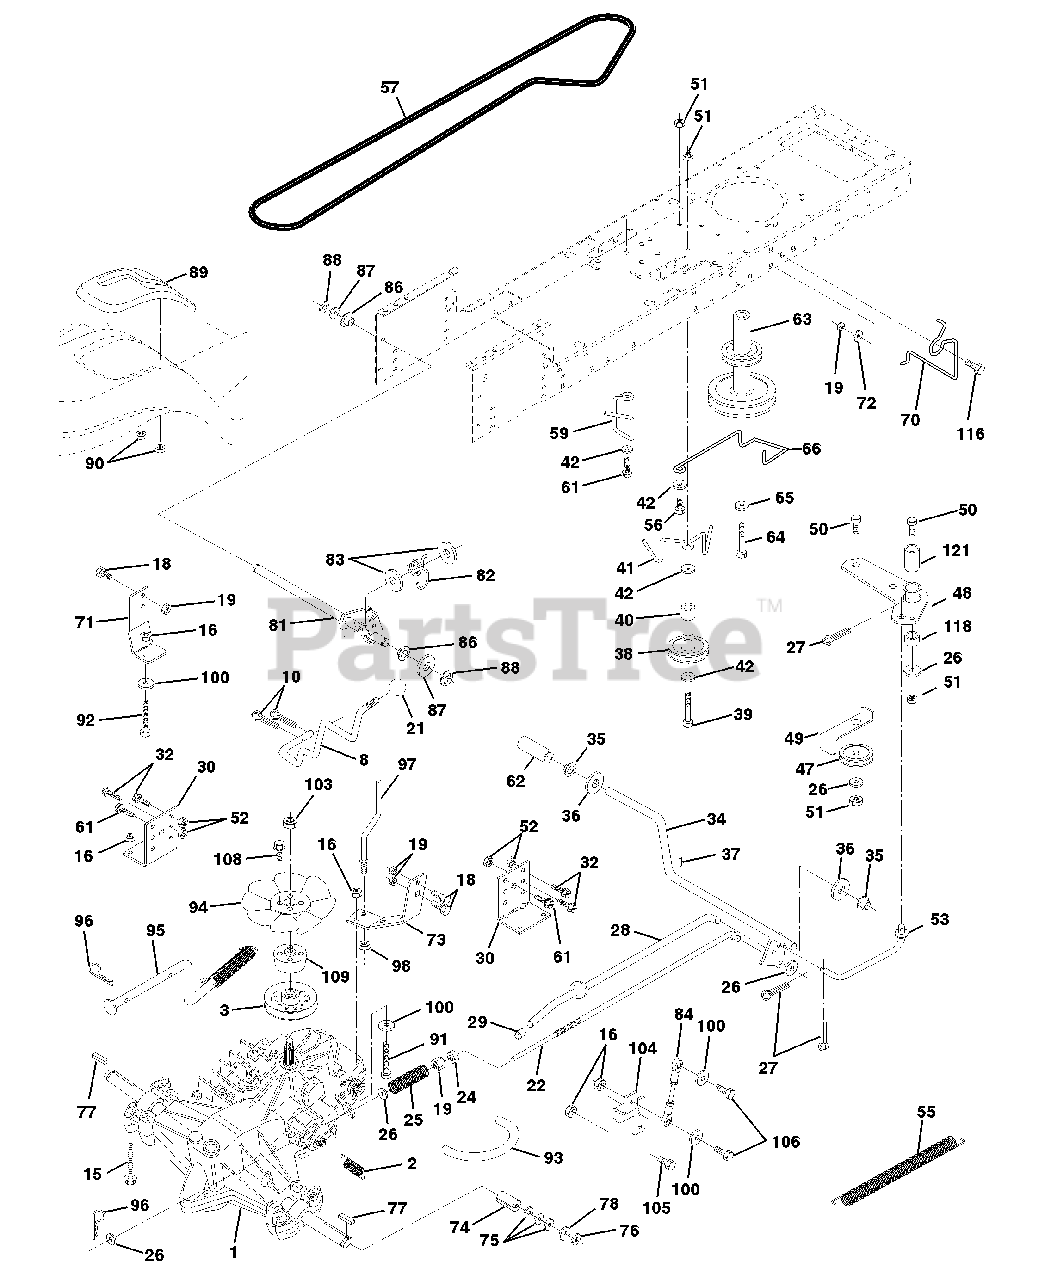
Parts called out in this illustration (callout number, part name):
1	Transaxle Assembly
2	Spring, Return, Brake
3	Pulley, Transaxle
8	Rod Shift Fender STLT
10	Pin Cotter 1/8 x 1 CAD
15	Bolt Hex Flghd 5/16-18 Gr 5
16	Nut Lock Hex W/Ins 5/16-18 Unc P
18	Bolt Fin Hex 3/8-16 Unc x 1 Gr. 5
19	Nut Lock Hex W/Wsh 3/8-16 Unc
21	Knob 1/2-13
22	Rod, Brake Hydro
24	Nut
25	Spring, Brake Rod
26	Washer
27	Pin Cotter 1/8 x 3/4 CAD.
28	Rod, Parking Brake
29	Cap, Parking Brake
30	Bracket, Transaxle
32	Bolt Hex Hd 5/16-18 Unc x 3/4
34	Shaft, Foot Pedal
35	Bearing, Nylon
37	Pin, Roll
38	Pulley, Idler, Flat
40	Spacer, Split
41	Keeper, Belt Retainer
42	Washer 13/32 x 13/16 x 12 Gauge
47	Pulley, Idler, V-Groove
48	Bellcrank Assembly
49	Retainer, Belt
50	Bolt
51	Nut Crownlock 3/8-16
52	Nut Crownlock 5/16-18
53	Link, Clutch
55	Spring, Return, Clutch
56	Bolt Fin Hex 3/8-16 Unc x 1-1/4
57	V-Belt, Ground Drive
59	Keeper, Center Span
61	Screw Thdrol. 3/8-16 x 3/4 Ty. TT
62	Cover, Pedal
63	Pulley, Engine
64	Bolt, Hex
65	Washer
66	Keeper, Belt Engine Flproof
70	Keeper Belt Engine
71	Strap Torque Lh Hydro 500 18"
72	Washer 13/32 x 1-1/4 x 12 Gauge
73	Strap Torque Rh Hydro 500 18"
74	Spacer, Split
75	Washer 25/32 x 1-1/4 x 16 Gauge
77	Key, Square
78	Washer 25/32 x 1-5/8 x 16 Gauge
81	Shaft Asm. Cross Hydro 500
82	Spring Torsion T/A
83	Washer 17/32 x 3/4 x 16 Ga.
84	Rod, Tie Hydro Sph Ball 500
86	Bushing Rod Strig. 629/632 ID
87	Washer 21/32 x 1-1/4 x 16 Ga.
88	Ring Klip #5304-62
89	Console, Shift Hydro STLT
90	Nut Self-Thd Wsh-Hd 1/4 Zinc
91	Bolt Fin Hex 5/16-18 x 2-1/4
92	Bolt Fin Hex 5/6-18 Unc x 1-1/2
93	Line Fuel Hydro 4"
94	Fan, Hydro 7"
95	Control Asm. Bypass Hydro
96	Retainer Spring 1" Zinc/Cad
97	Keeper Belt Rh Hydro 500
98	Nut Keps Hex 3/8-16 Unc
100	Washer 11/32 x 3/4 x 16 Ga.
103	Nut, Hex Jam Toplock 1/2-20 Unf
104	Arm, Control Pump
105	Screw Cap Hex 5/16 x 18 x 1
106	Bolt Fin Hex 5/16-18 Unc x 1-1/4
108	Screw Hex Wh Hd #10-24 x 1-5/8
109	Adaptor Fan/Hydro Lt Hyd Alum
116	Bolt, RDHD SQ Neck 3/8-16 x 1.25
118	Spacer Bellcrank
121	Nyliner Clutching STL
